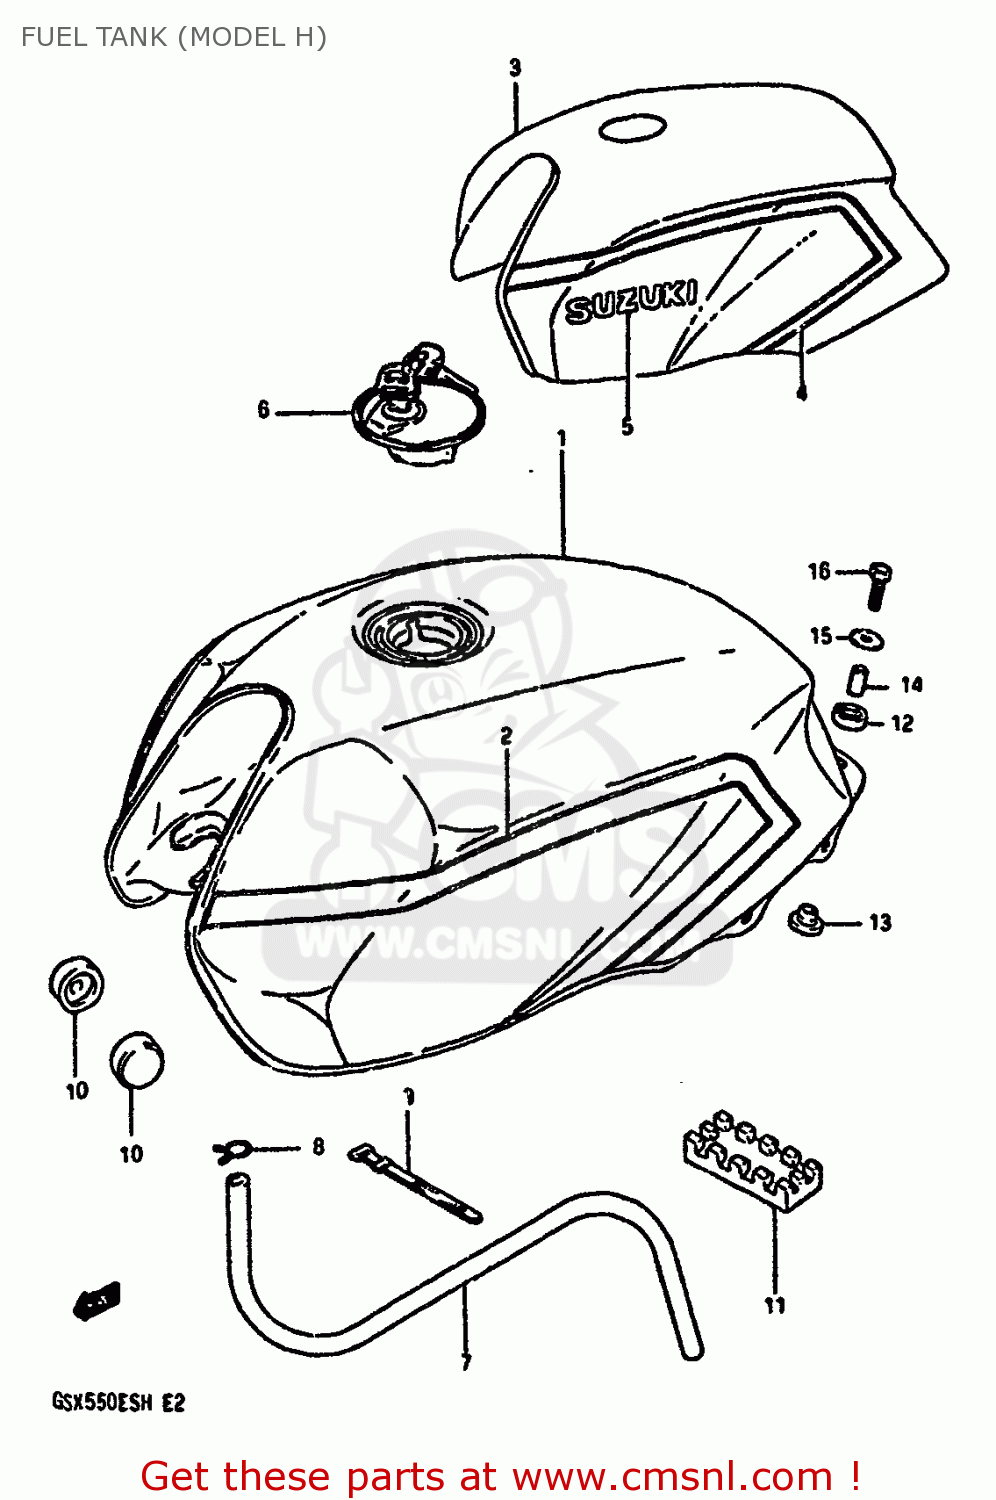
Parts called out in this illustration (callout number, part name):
1	TANK ASSY,FUEL
2	TAPE SET,FUEL TANK
3	TANK ASSY,FUEL
4	TAPE SET,FUEL TANK
5	EMBLEM
6	CAP ASSY,FUEL TANK
7	HOSE,FUEL
8	CLIP
9	CLAMP(L:187)
10	CUSHION
11	CUSHION,FUEL TANK
12	CUSHION
13	CUSHION
14	SPACER (6.4X9X20)
15	WASHER (6.5X24X1.6)
16	BOLT
